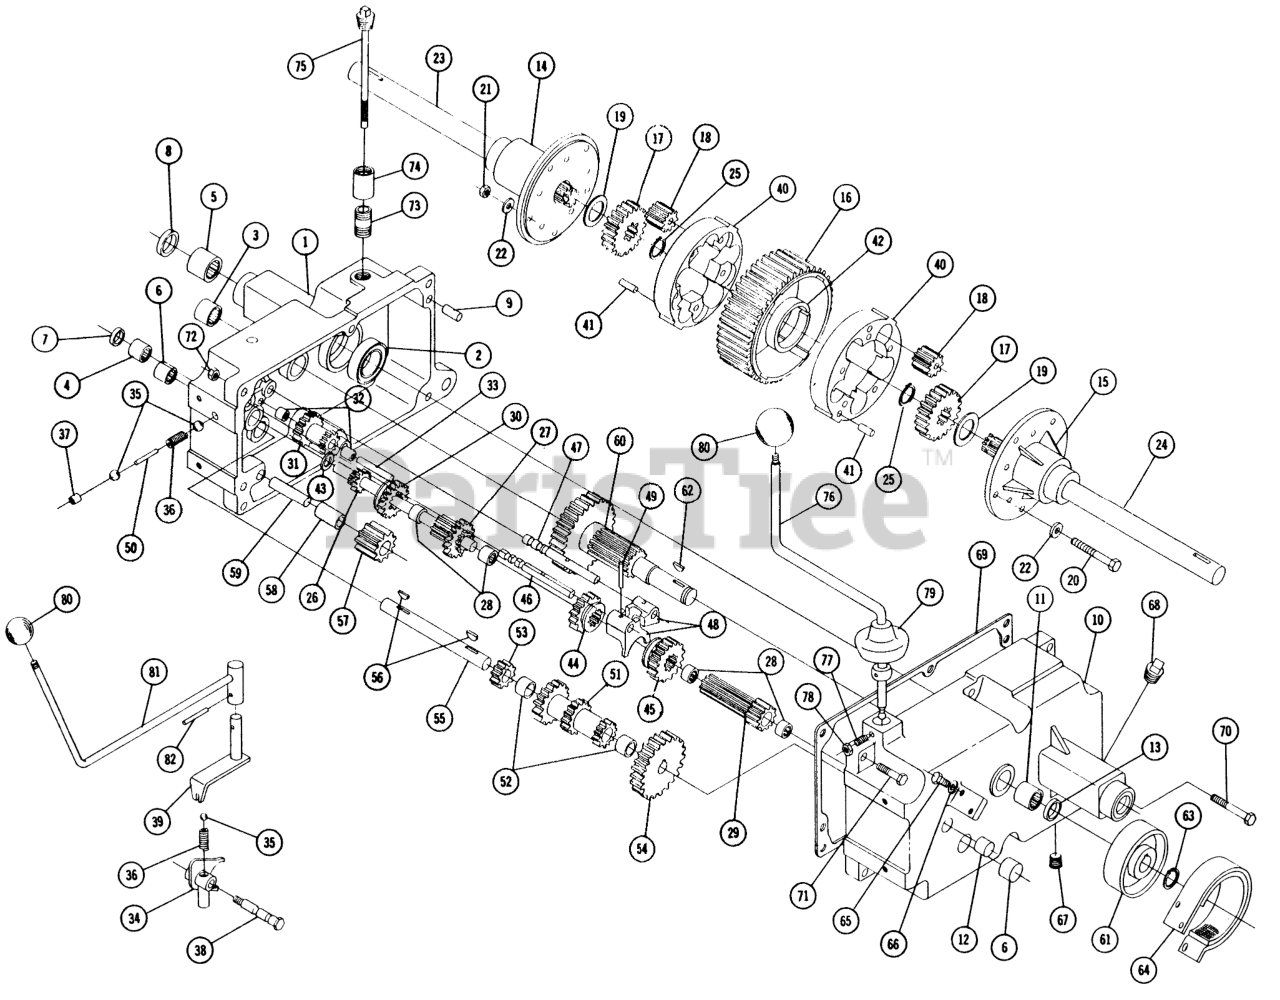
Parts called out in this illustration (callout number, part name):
1	Case RH
2	BALL BRG 1 1/2 I.D.
3	BEARING-NEEDLE
4	BEARING-NEEDLE
5	Bearing-Axle
6	BEARING-NEEDLE
7	Seal 5/8 Shaft
8	Seal
9	PIN-DOWEL
10	Case L.H.
11	Bearing-Needle
12	Bearing Needle
13	Seal
14	End Cap-RH
15	End Cap-LH
16	Gear-Ring
17	SIDE GEAR
18	PINION
19	THRUST WASHER
20	Bolt Hex 3 1/4
21	3/8-16 E.S.
22	Washer
23	Axle, R.H.
24	Axle, L.H.
25	SNAP RING
26	SHAFT-INPUT
27	GEAR
28	BEARING-NEEDLE
29	GEAR
30	GEAR-SLIDING
31	Gear
32	BEARING-NEEDLE
33	GEAR-SHAFT REDUCTION
34	Shift Fork
35	BALL-DETENT
36	Spring
37	CUP-PLUG
38	BOLT-DETENT
39	SHIFT ASM
40	Body
41	SPIROL ROLL PIN
42	Spring
43	WASHER-THR
44	GEAR-HI AND 2ND
45	GEAR-LOW AND REVERSE
46	RAIL-SHIFT
47	RAIL-REAR SHIFT
48	FORK-SHIFT
49	PIN-ROLL
50	PIN-SHIFT
51	Cluster Gear
52	BUSHING-BRONZE
53	GEAR-PINION
54	GEAR-CLUSTER SHAFT
55	Cluster Shaft
56	Key
57	GEAR/BUSHING ASM-REVERSE IDLER
58	BUSHING
59	PIN-DIFFERENTIAL
60	Gear-Brake Shaft
61	Brake Drum
62	WOODRUFF KEY
63	Snap Ring
64	BRAKE BAND & LINER A
65	Bolt-1/4-20 x 5/8
66	Lockwasher
67	PLUG 1/4 PIPE ALLEN
68	Plug
69	GASKET-TRANSMISSION
70	Bolt Hex 3/8-16 x 1
71	Bolt, 3/8 16 x 2
73	Nipple Close 1/2 Pipe
74	Coupling 1/2 Pipe
75	Dipstick
76	Shift Stick
77	SETSCREW
78	Nut 1/4-20
79	COVER-DUST
80	Knob
81	Handle-Shift
82	PIN-SPIROL
